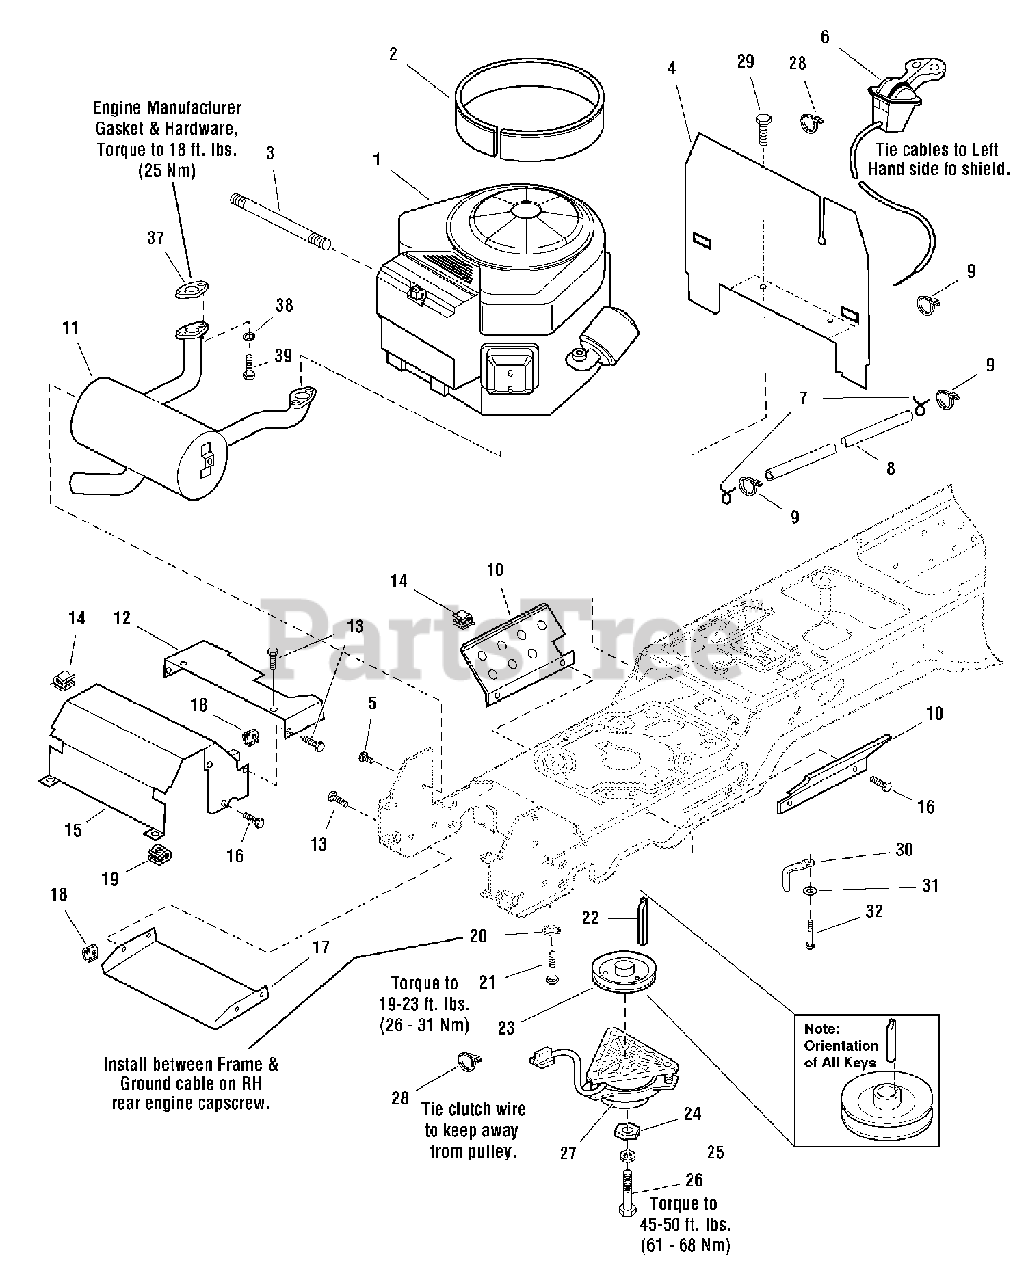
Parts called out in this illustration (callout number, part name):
1	* ENGINE, 23HP B&S VANGUARD Twin Mod. 386777-0111-E1
2	SEAL, Circle
3	HOSE, Oil Drain
4	BULKHEAD
5	CAPSCREW, Hex Head Taptite, 5/16-18 x 1/2
6	CONTROL, Throttle Double
7	CLAMP, Hose, .50" DIA, Type E
8	HOSE, 59" Long
9	TIE, Self Locking, .184" WD, 15.00" LG, Black
10	SHIELD
11	MUFFLER
12	DUCT, Muffler Extension
13	CAPSCREW, Hex Head Flange Lock, 1/4-20 x 5/8
14	CLIP, Wire, .125 DIA, .035/.050
15	DUCT, Muffler Top
16	SCREW, Hex Head Taptite, 1/4-20 x 3/8
17	SHIELD, Muffler Bottom
18	NUT, Speed, 1/4-20
19	NUT, Speed, Lug Type, 5/16-18
20	LOCKWASHER, External Tooth, 3/8
21	CAPSCREW, Hex Head Taptite, 3/8-16 x 1-1/2
22	KEY, HI-PRO, .250X2.500
23	PULLEY & HUB ASSEMBLY, 4-1/2 OD
24	WASHER, Hex, .453" ID X 1.50" A/F, .250" TH
25	LOCKWASHER, 7/16
26	CAPSCREW, Hex Head, 7/16-20 x 2-3/4
27	CLUTCH, Electric, Big Brake OGURA
28	TIE, Self Locking, .09" WD, 3.62" LG, Black Zytel
30	RETAINER, Clutch, .330" DIA, 2.85 X 2.67 Blk
31	WASHER, .375" (0.41" ID X 0.87" OD X .08" THK) Blk
32	CAPSCREW, Hex Head, 3/8-16 x 1
37	* GASKET, Muffler
38	LOCKWASHER, 5/16
39	CAPSCREW, Socket Head, 5/16-18 x 7/8, G8
